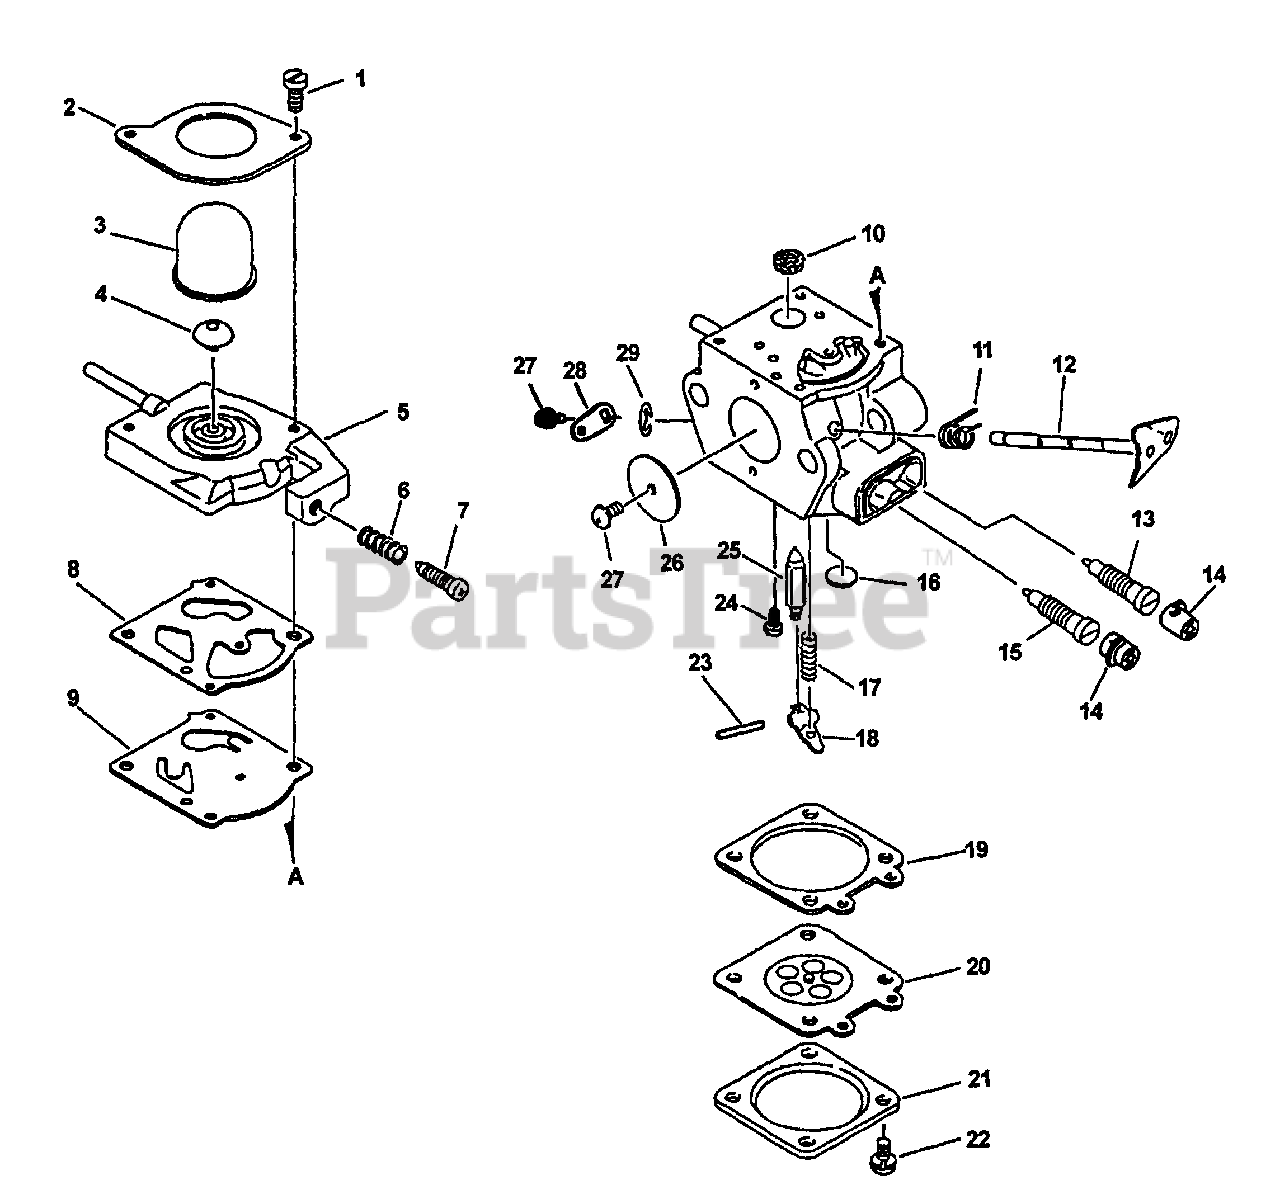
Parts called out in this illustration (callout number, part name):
1	SCREW, PUMP COVER
2	RETAINER, PURGE BULB
3	BULB, PURGE
4	VALVE, CHECK
5	COVER, PUMP
6	SPRING, IDLE ADJUST
7	SCREW, IDLE ADJUST
8	GASKET, PURGE
9	DIAPHRAGM, PURGE
10	STRAINER
11	SPRING, THROTTLE RETURN
12	SHAFT, THROTTLE
13	NEEDLE - HIGH SPEED
14	CAP, LIMITER
15	NEEDLE - LOW SPEED
16	PLUG, WELCH
17	SPRING, METERING LEVER
18	LEVER, METERING
19	GASKET, METERING
20	DIAPHRAGM, METERING
21	COVER, METERING
22	SCREW, METERING COVER
23	PIN, METERING LEVER
24	SCREW, METERING LEVER PIN
25	VALVE, INLET NEEDLE
26	VALVE, THROTTLE
28	LEVER, THROTTLE
29	RING, RETAINING
